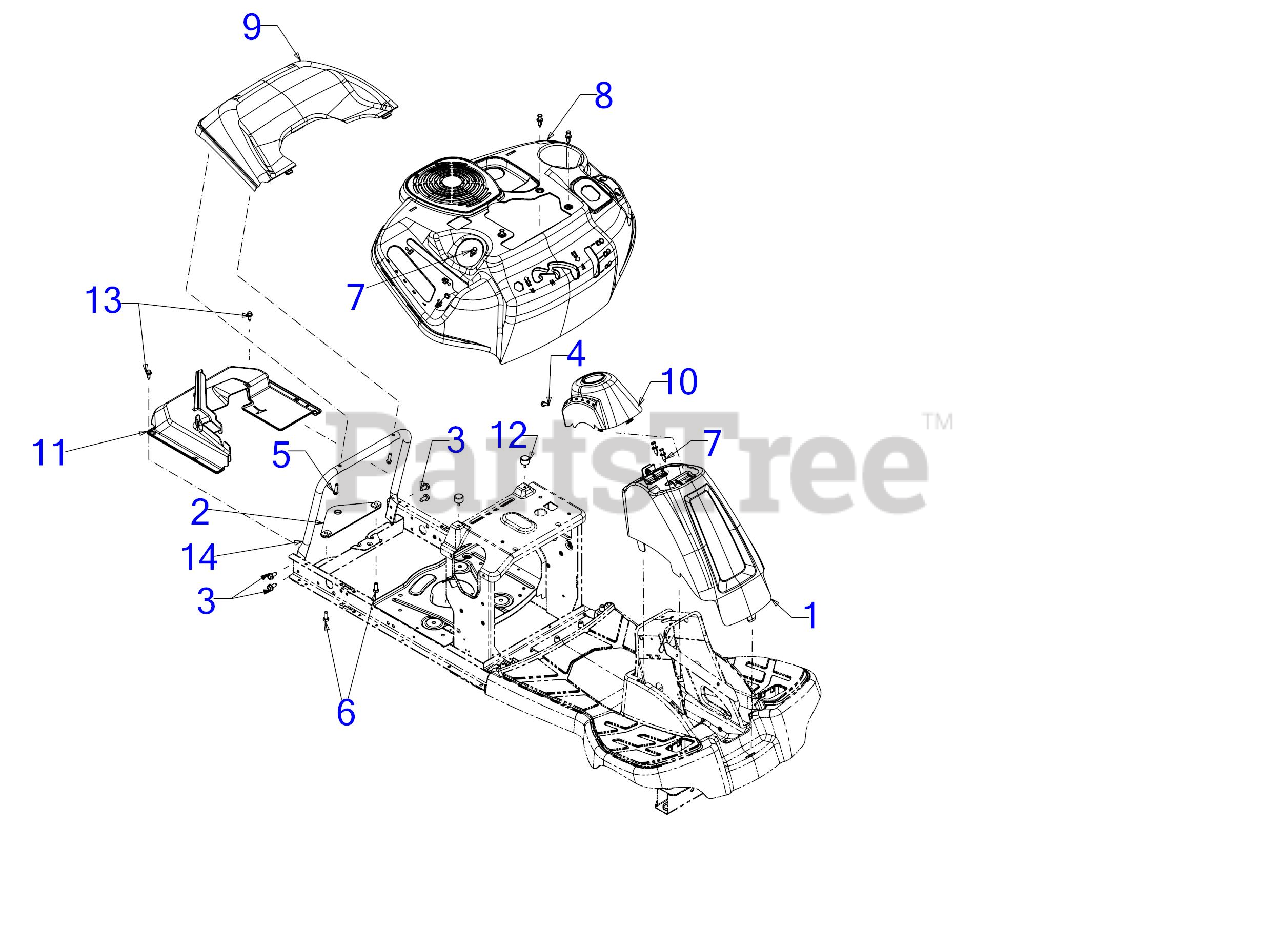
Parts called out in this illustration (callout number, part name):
1	COLUMN COVER ASSEMBLY
3	SCREW 5/16-18 x .750
4	SCREW 1/4-20X.75
5	SCREW 1/4-15 x 1.00
6	SCREW 5/16-18 x .75 GR5
7	PLASTIC RIVET
8	FENDER
9	REAR COVER
10	STEERING COLUMN CAP (SEARS RED)
11	DRIVE OVER REAR
12	BUMPER .62 DIA x .50
13	SHOULDER SCREW
